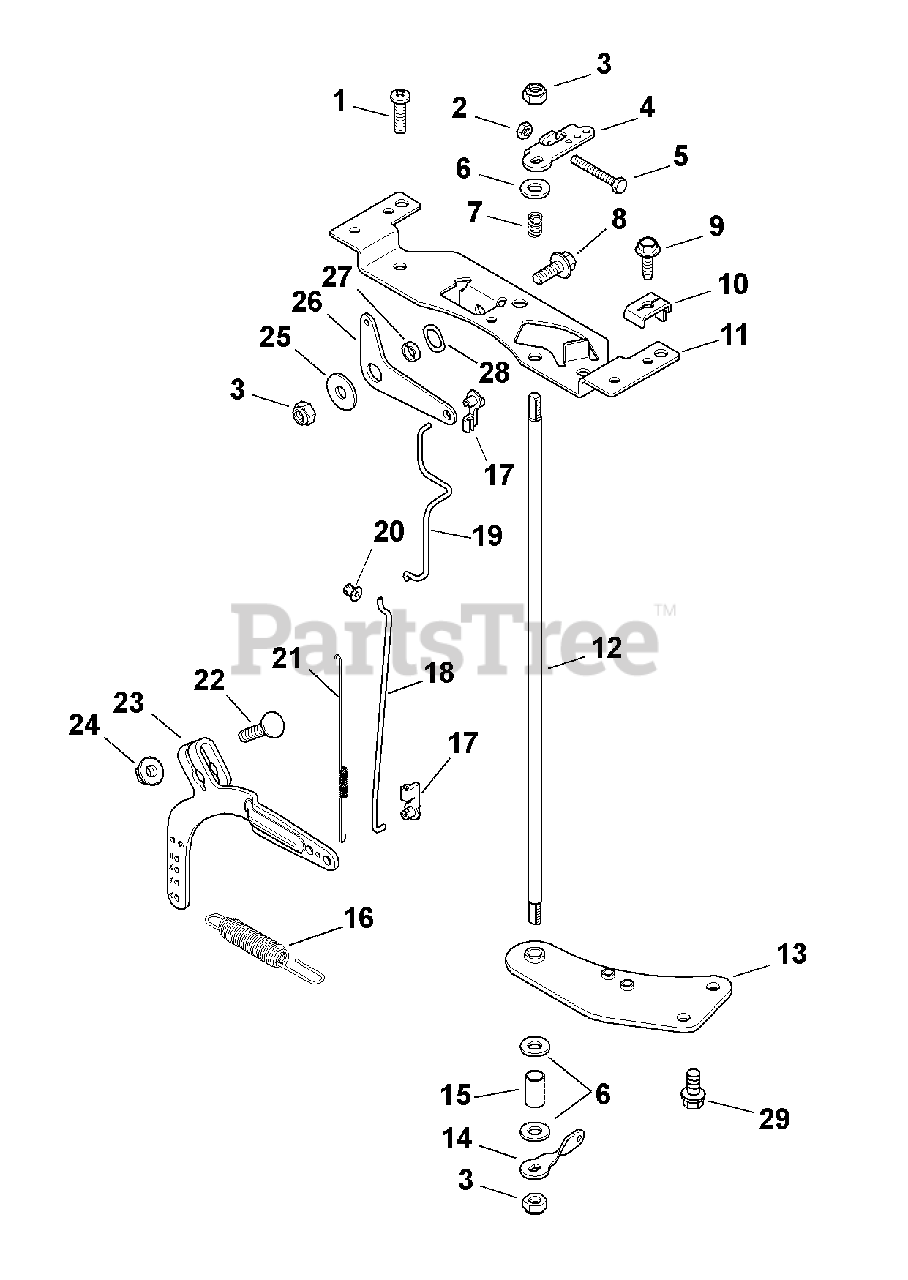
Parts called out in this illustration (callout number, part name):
1	Screw, Phl Hd 11-16 x 3/4"
2	Nut, M4 x 0.7
3	Nut, Lock M6 x 1.0
4	Lever, Throttle Control
5	Screw, Cap M4 x 0.7 x 30
6	Washer, Flat 1/4"
7	Spring, Throttle Shaft
8	Screw, Flg M6x1.0x16
9	Screw, Flg Thd Frm M5 x 0.8 x 16
10	Clamp, Cable
11	Bracket, Control
12	Shaft, Throttle
13	Bracket, Throttle Shaft
14	Lever, Throttle Control
16	Spring, Governor
17	Bushing, Throttle Linkage
18	Linkage, Throttle
19	Linkage, Choke
20	Bushing, Linkage Retaining
21	Spring, Linkage
22	Bolt, Rd Hd Sq Neck M6x1.0x25
23	Lever, Governor
24	Nut, FLG M6 x 1.0
25	Washer, Flat 1/4"
26	Lever, Choke
28	Washer, Spring 3/8"
29	Screw, Flg Thd Frm M6 x 1.0 x16
